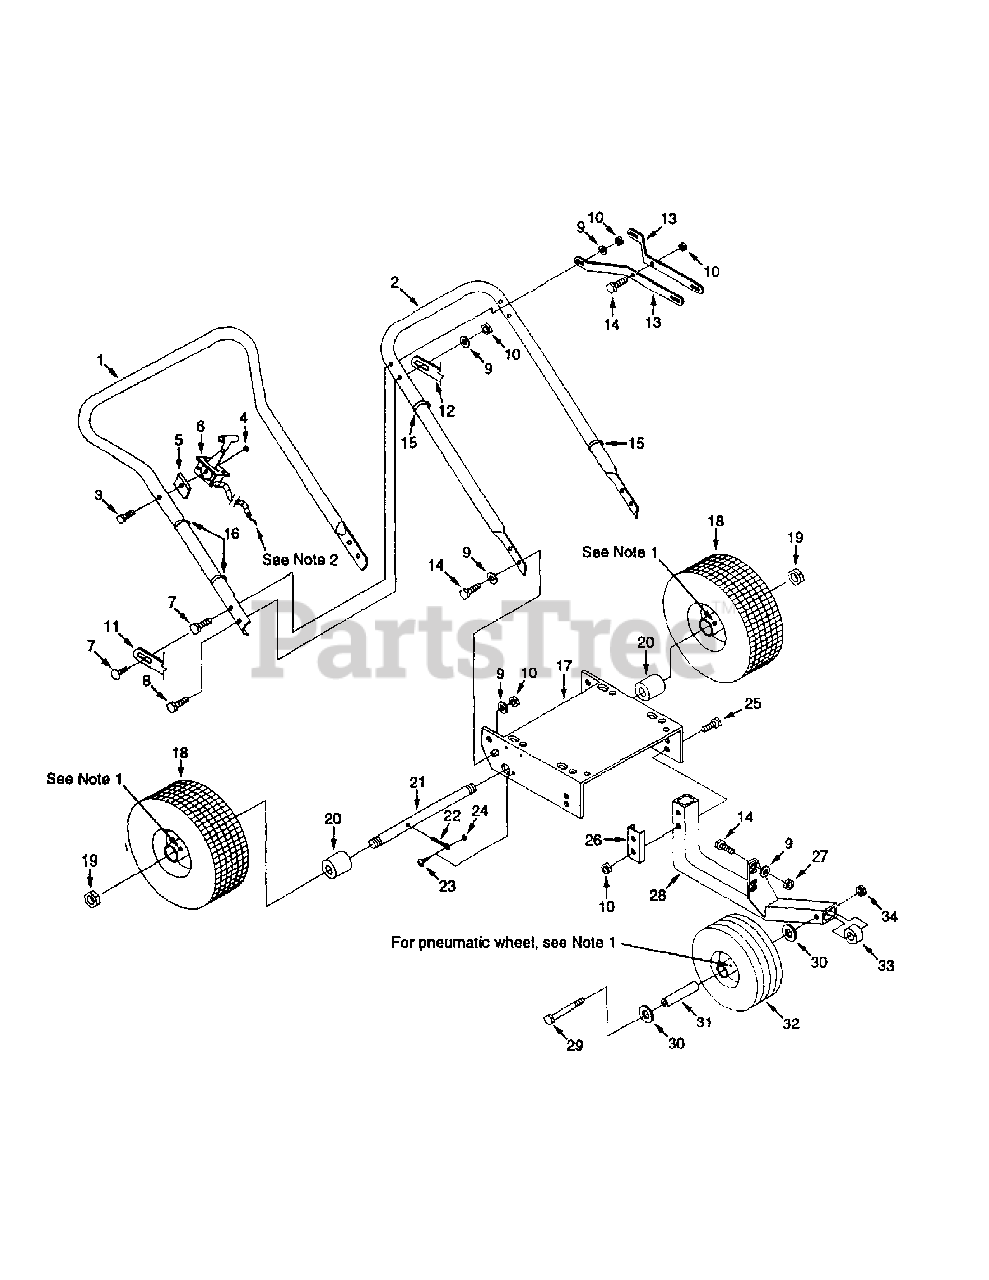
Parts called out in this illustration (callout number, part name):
1	Upper Handle
2	Lower Handle
3	Cap Screw, 1/4-20 x 1-1/2 Hex Head
4	Hex Nut, 1/4-20 Side Lock
5	Spacer, Throttle Mounting
6	Control Cable
7	Cap Screw, 5/16-18 x 1-1/2 Hex Head
8	Cap Screw, 5/16-18 x 1-3/4 Hex Head
9	Flat Washer, 5/16 SAE
10	Hex Nut, 5/16-18 Side Lock
11	Center Brace
12	Center Brace
13	Center Brace, Offset
14	Cap Screw, 5/16-18 x 3/4 Hex Head
15	Clamp, Throttle Cable
16	Clamp, Throttle Cable
17	Engine Base Plate
18	Wheel Assembly, 11 x 4.00-4
19	Hex Nut, 5/8-18 Nylock, Thin
20	Axle Spacer
22	Cotter Pin, 3/16 x 1-1/4
23	Machine Screw, #10-32 x 3/4 Round Head
24	Hex Nut, 5/8-18 Nylock, Thin
25	Cap Screw, 5/16-18 x 1-1/2 Hex Head
26	Support Plate, Front Wheel Frame
27	Hex Nut, 5/16-18 Stover Lock
28	Frame, Solid Front Wheel
28	Frame, Pneumatic Front Wheel
29	Cap Screw, 5/16-18 x 4 Hex Head
29	Cap Screw, 3/8-16 x 5 Hex Head
30	Flat Washer, 5/16 USS
30	Flat Washer, 3/8 USS
31	Sleeve, Solid Front Wheel
31	Sleeve, Pneumatic Front Wheel
32	Solid Wheel, 5 x 2 wutg 1/2 Bore
32	Pneumatic Tire L Wheel Assembly W/Bearing
33	Spacer, Inside Tube
34	Hex Nut, 5/16-18 Side Lock
34	Hex Nut, 3/8-16 Nylock
